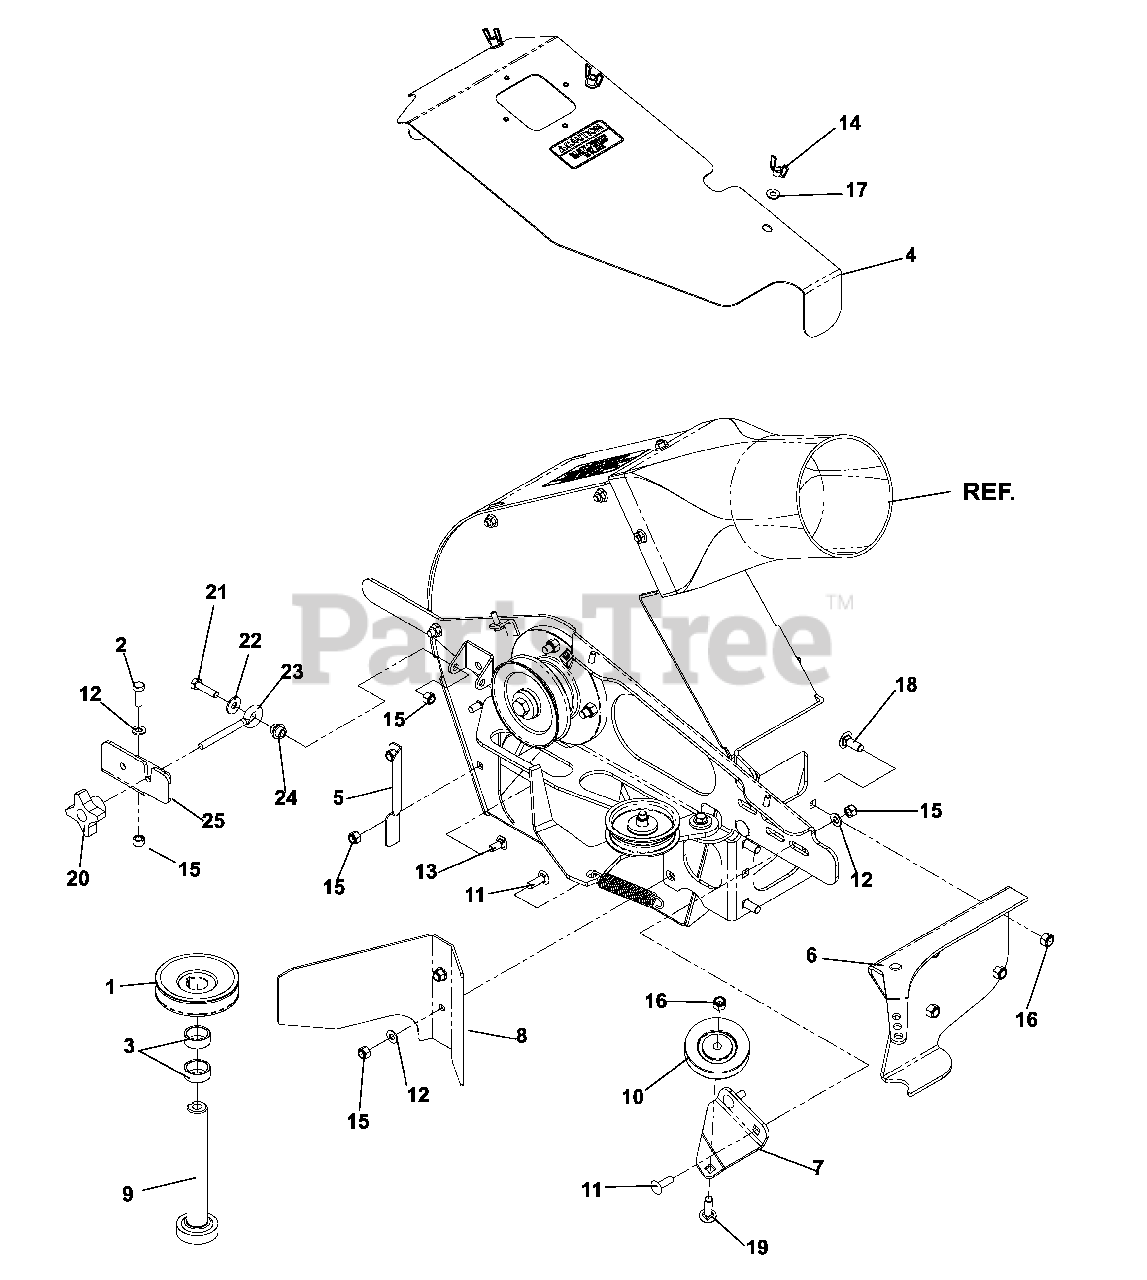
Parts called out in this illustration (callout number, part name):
1	V-PULLEY
2	HCS 5/16C X 1
3	HUB BEARING SPACER
4	GUARD ASSEMBLY. 52"
6	PIVOT WLDT
7	FIXED IDLER BRKT.
8	BLOCK OFF PLATE
9	SHAFT LONG
10	PULLEY, IDLER 3 METAL
11	RHSSNB 5/16C X 1.0
12	FLAT WASHER 5/16 SAE
13	BOLT 5/16C X 3/4" CARRIAGE
14	WING NUT 1/4
15	NUT 5/16 NYLOC
16	NUT 3/8-16 NYLOC
17	1/4` SAE FLAT WASHER
18	RHSNB 3/8C X 1
19	RHSNB, 3/8-16 X 1-1/2
20	SEAT KNOB 5/16-18
21	HCS 5/16C X 1 1/4
22	WASHER 5/16 FLAT
23	EYE BOLT 5/16 X 3.50
24	SPRING CAP
25	LATCH RECEIVER
